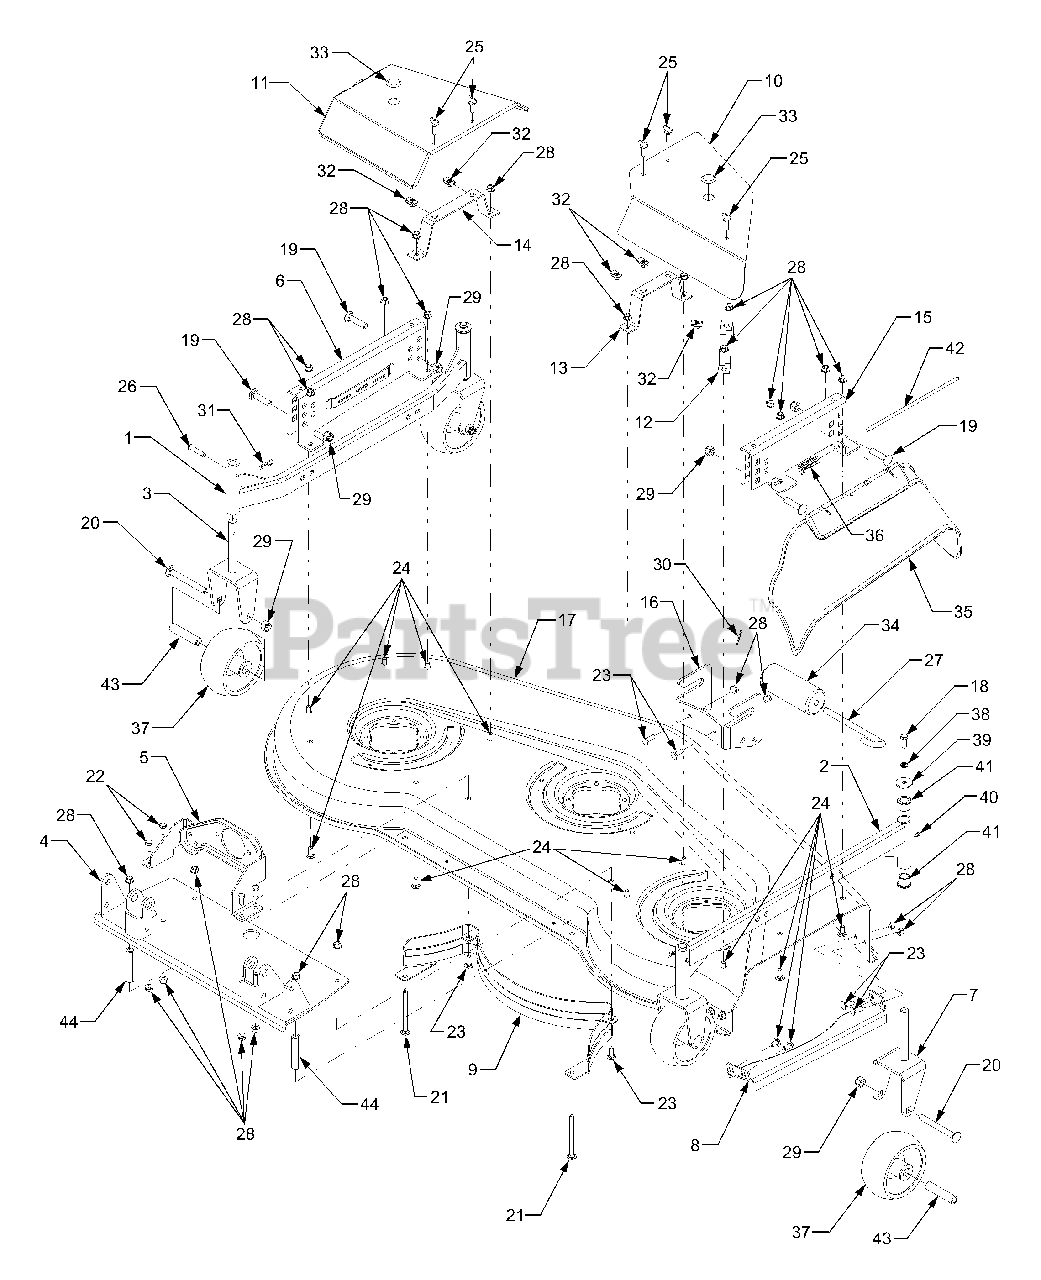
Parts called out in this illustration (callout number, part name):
1	Axle, Caster, LH
2	Axle, Caster, RH
3	Wheel Yoke, Rear
4	Bracket, Mounting
5	Bracket, Gear Box
6	Bracket, Caster LH
7	Wheel Yoke, Front
8	Guard, Finger
9	Baffle, Rear Inner
10	Cover, Belt (R.H.)
11	Cover, Belt (L.H.)
12	Bracket, Belt Cover Mtg.
13	Bracket, Belt Cover Mtg.
14	Bracket, Belt Cover Mtg. LH
15	Bracket, Caster RH
16	Bracket, Front Roller
17	Deck
18	Screw, Hex Cap 3/8-16 x 1.0 GR5
19	Screw, Carriage 1/2-13 x 2.125 GR5
20	Screw, Carriage 1/2-13 x 4.5 GR5
21	Screw, Carriage 3/8-16 x 4.50 GR5
22	Screw, Hex Cap Lock 3/8-16 x .75 GR5
23	Carriage, Bolt 3/8-16 x 1.0
24	Carriage, Bolt 3/8-16 x .75
25	Screw, Thumb Adjust 5/16-18 x 1
26	Pin, Clevis, 3/8 x 1.75
27	Pin, Roller 1/2 x 7.31
28	Nut, Flange Lock 3/8-16
29	Nut, Hex Nylon Lock 1/2-13 GR8
30	Pin, Cotter 1/8 x 1.0
31	Pin, Internal Cotter
32	Nut, "U" 5/16-18
33	Plug, Button
34	Roller, Front
35	Deflector, Chute
36	Spring, Torsion
37	Caster, Wheel w/Bearings
38	Washer, Lock 3/8" I.D.
39	Washer, Flat, .39 x 1.5 x .134
40	Fitting, Lube
41	Bearing, Flange, .754 ID
42	Rod, Deflector Chute
43	Axle, Caster Wheel
44	Spacer, .505 x .75 x 3.31Lg.
